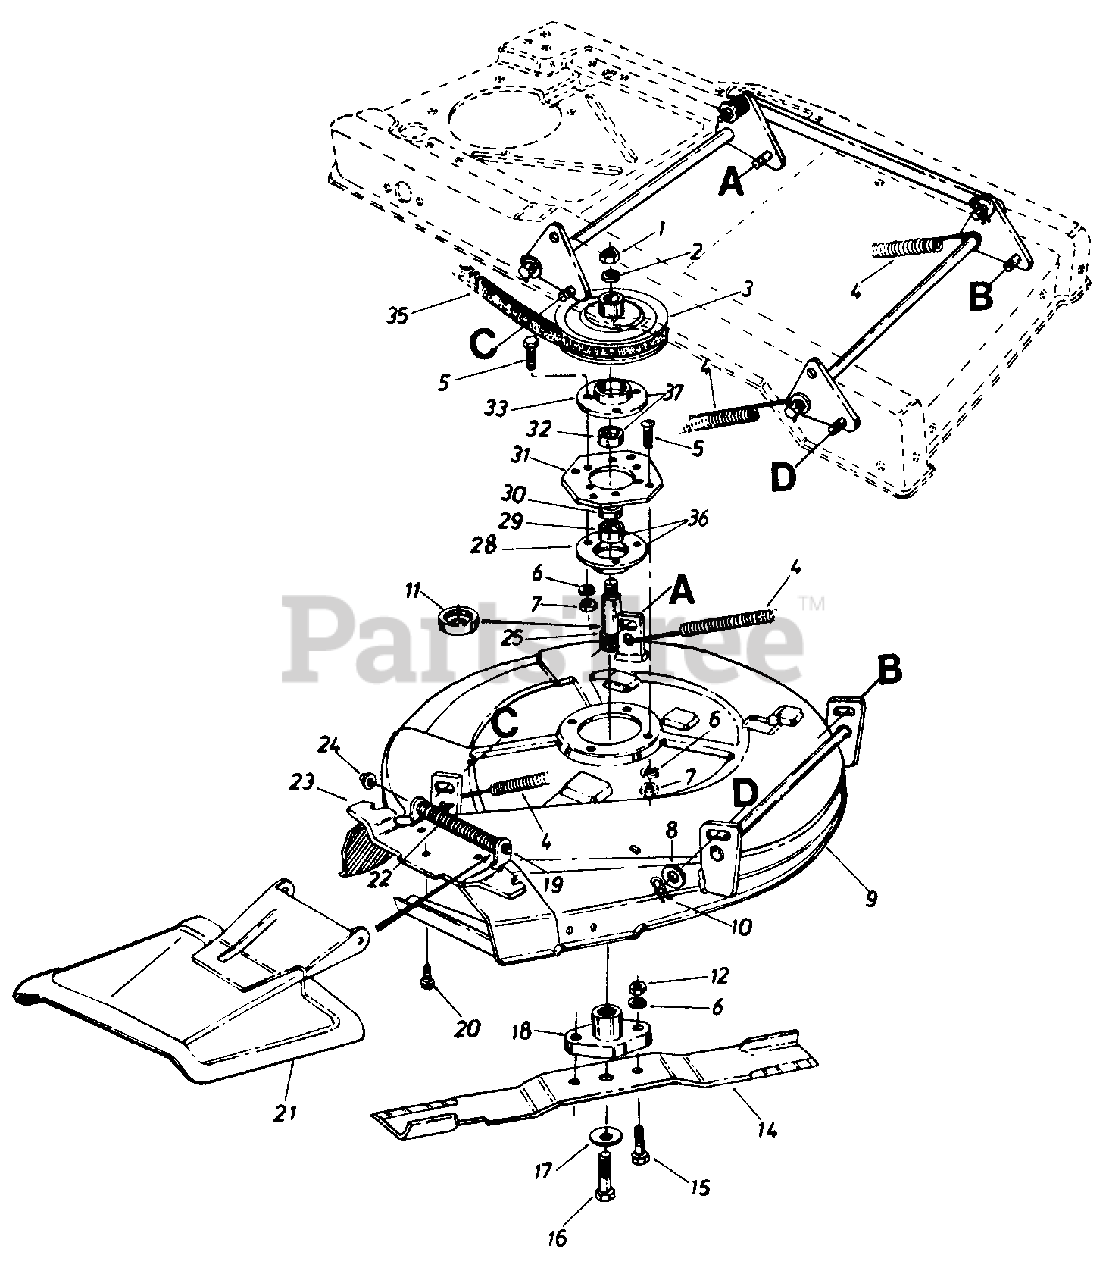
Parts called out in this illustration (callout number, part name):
1	Hex Jam Nut 5/16-18 Thd.
2	Bell-Wash. .630" I.D. x 1.25n O.D.
3	518'1 "V"-Pulley .751' I.D. x 9.51' ??
4	Extension Spring .56" O.D. x 1 0.5
5	Hex Bolt 5/16-18 x .75 Lg.
6	L-Wash. 5/16" I.D.
7	Hex Nut 5/16-18 Thd.
8	Fl-Wash. .510n I.D. x 1.0" O.D.
9	26" Deck Ass'y.
10	Inter. Cotter Pin 1/2" Dia.
11	Bearing Shield
12	Hex Nut 5/16-24 Thd.
14	Blade 26"
15	Hex Bolt Special 5/16-24 x 1.0" Lg.
16	Hex Bolt 3/8-24 x l.00" Lg.
17	Bell-Wash. .391" I.D. x 1.38" O.D.
18	Blade Adapter
19	Hinge Pin
20	Hex Wash. Hd. TT-Scr. 1/4-20
21	Chute Cover Ass'y.
22	Torsion Spring
23	Adapter Plate
24	Cap Speed Nut 1/4" Rod
25	Blade Spindle 4.42" Lg.
28	Bearing Housing 1.85
29	Ball Brg. .787" I.D. x 1.85" O.D.
30	Spacer 1.0" O.D. x .790" I.D. x 850n Lg.
31	Spindle Mounting Plate
32	Ball Brg. .787" I.D. x 1.85" O.D.
33	Open Brg. Housing 1.85
35	"V"-Belt
36	Brg. Hsg. Ass'y.
37	Brg. Hsg. Ass'y.
